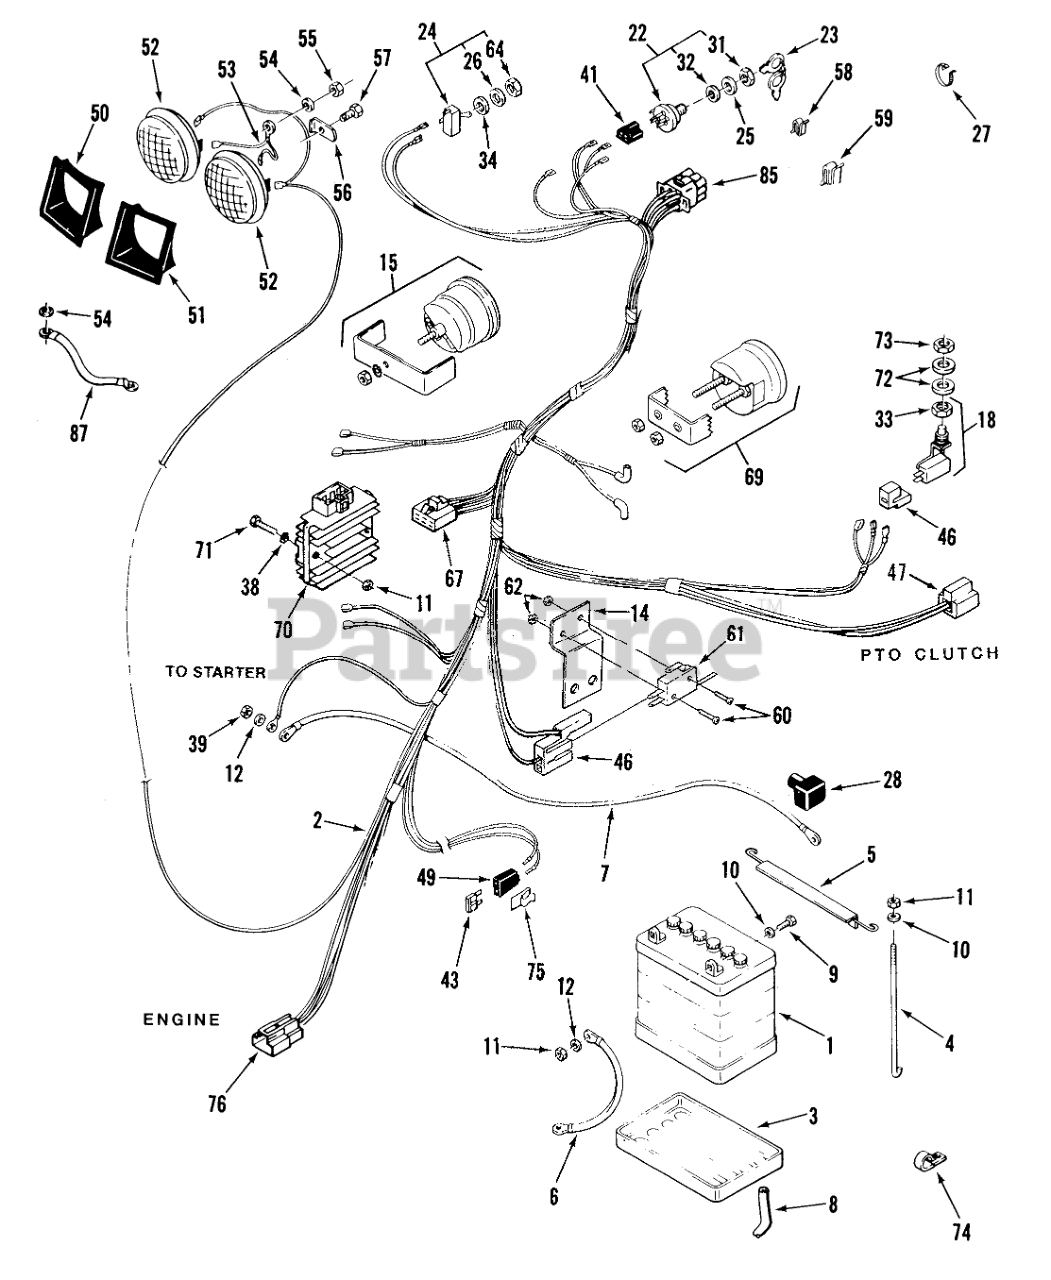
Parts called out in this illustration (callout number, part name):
1	Battery
3	TRAY-BATTERY
5	HOLDDOWN-BATTERY
6	WIRE - 14" BLACK
7	ASSY WIRE
8	TUBE-21" BATTERY DRAIN
9	Bolt
11	Nut
12	Washer
14	BRKT SWITCH BRAKE R
15	Hourmeter (Includes 108768 clamp,
18	Seat Switch
22	Ignition Switch (includes items 31 & 32)
23	Ignition Key
24	Light Switch (includes items 33 & 34)
25	Washer
26	Washer
27	PLASTIC TIE
28	Boot
32	LOCKWASHER
38	LOCKWASHER
39	Nut
41	CONNECTOR-5 WAY-SERV
43	FUSE-BLADE, 15 AMP
46	CONNECTOR BODY
47	CONNECTOR BODY
49	FUSE-BLOCK ASS'Y
50	BEZEL-HEADLIGHT, RH
51	BEZEL-HEADLIGHT, LH
52	HEADLAMP
53	LIGHT GROUND WIRE
54	Washer-Lock
55	Nut
56	LOCK-HEADLIGHT
57	Bolt
58	CLIP
59	SPEED CLIP
60	Screw
61	SWITCH
62	NUT HEX 4-40 ELAST
67	6 Terminal Connector 112-C Only
69	Voltmeter (Includes 109650 Clamp & 5924=10-32 Nut)
70	Voltage Regulator 252-H (Kawasaki #21066-2004)
71	HHCS 1/4-20X1" WHIZ
72	Washer
73	NUT-HEX SPECIAL
74	CLAMP
75	MOUNTING-CLIP CONN
76	3-CONTACT LOCK-TYPE
85	9-Terminal Connector
87	WIRE-LIGHT GROUND
